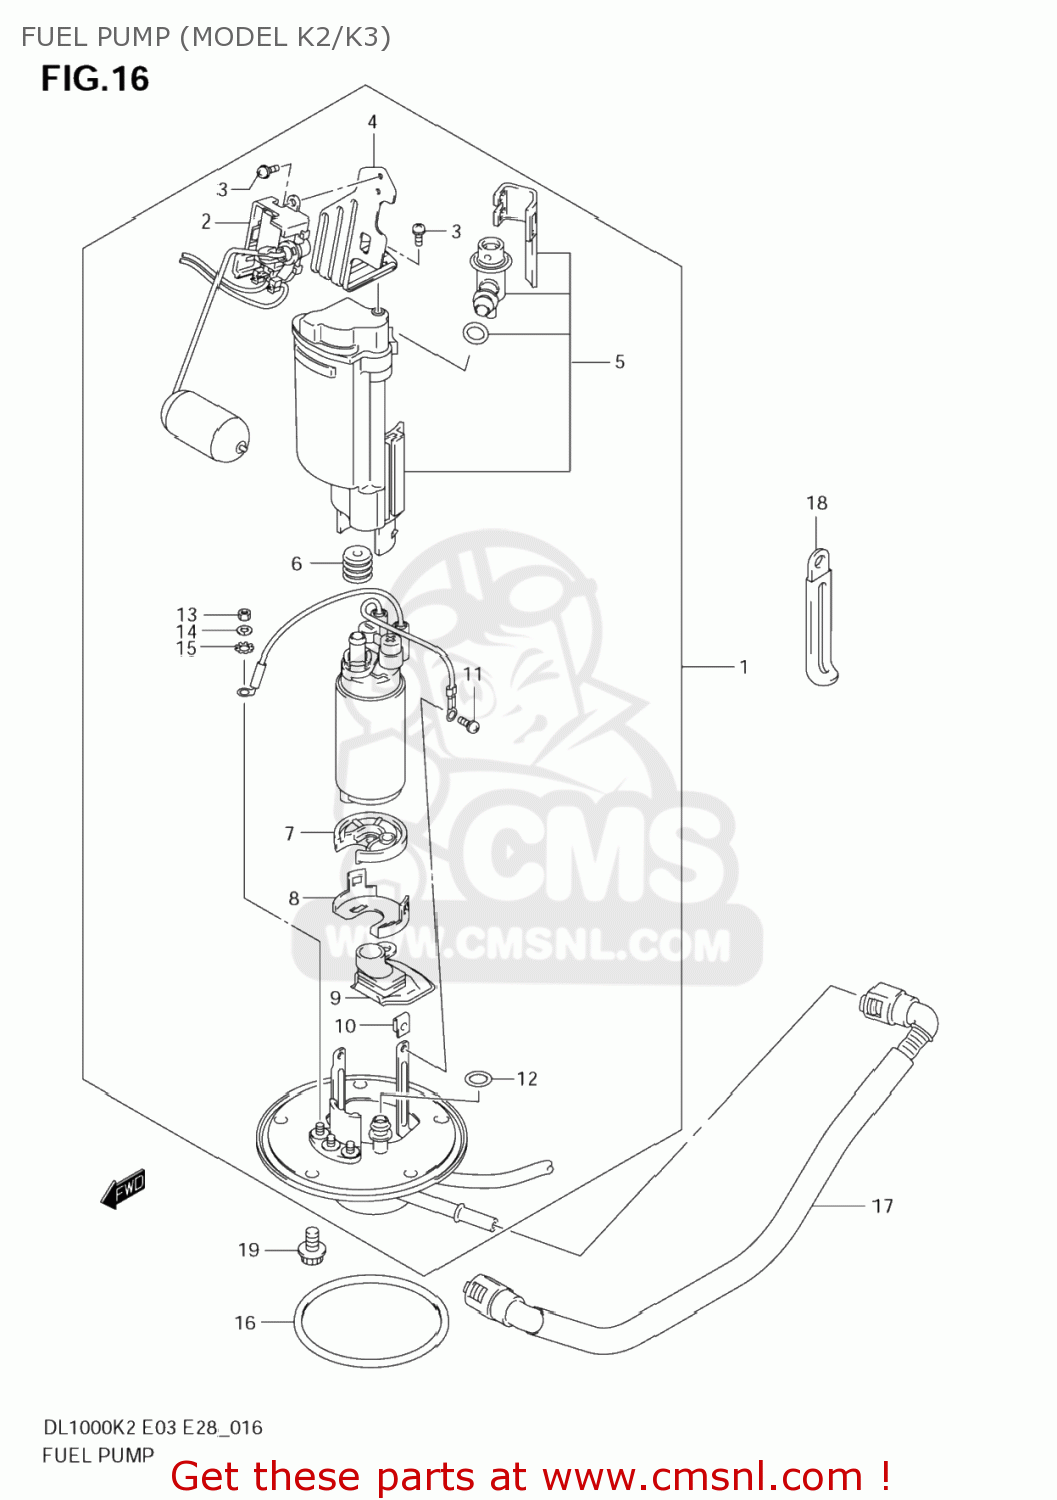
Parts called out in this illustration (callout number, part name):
1	PUMP ASSY,FUEL
2	GAUGE ASSY,FUEL LEVER
3	SCREW
4	BRACKET,FUEL GAUGE
5	FILTER,FUEL
6	BUSH,FUEL PUMP
7	CUSHION
8	HOLDER,FUEL PUMP
9	STRAINER,FUEL PUMP
10	NUT
11	SCREW
12	O RING
13	NUT
14	WASHER,SPRING
15	WASHER
16	O RING,FUEL PUMP
17	HOSE COMP,FUEL
18	CLAMP(L:65)
19	BOLT
